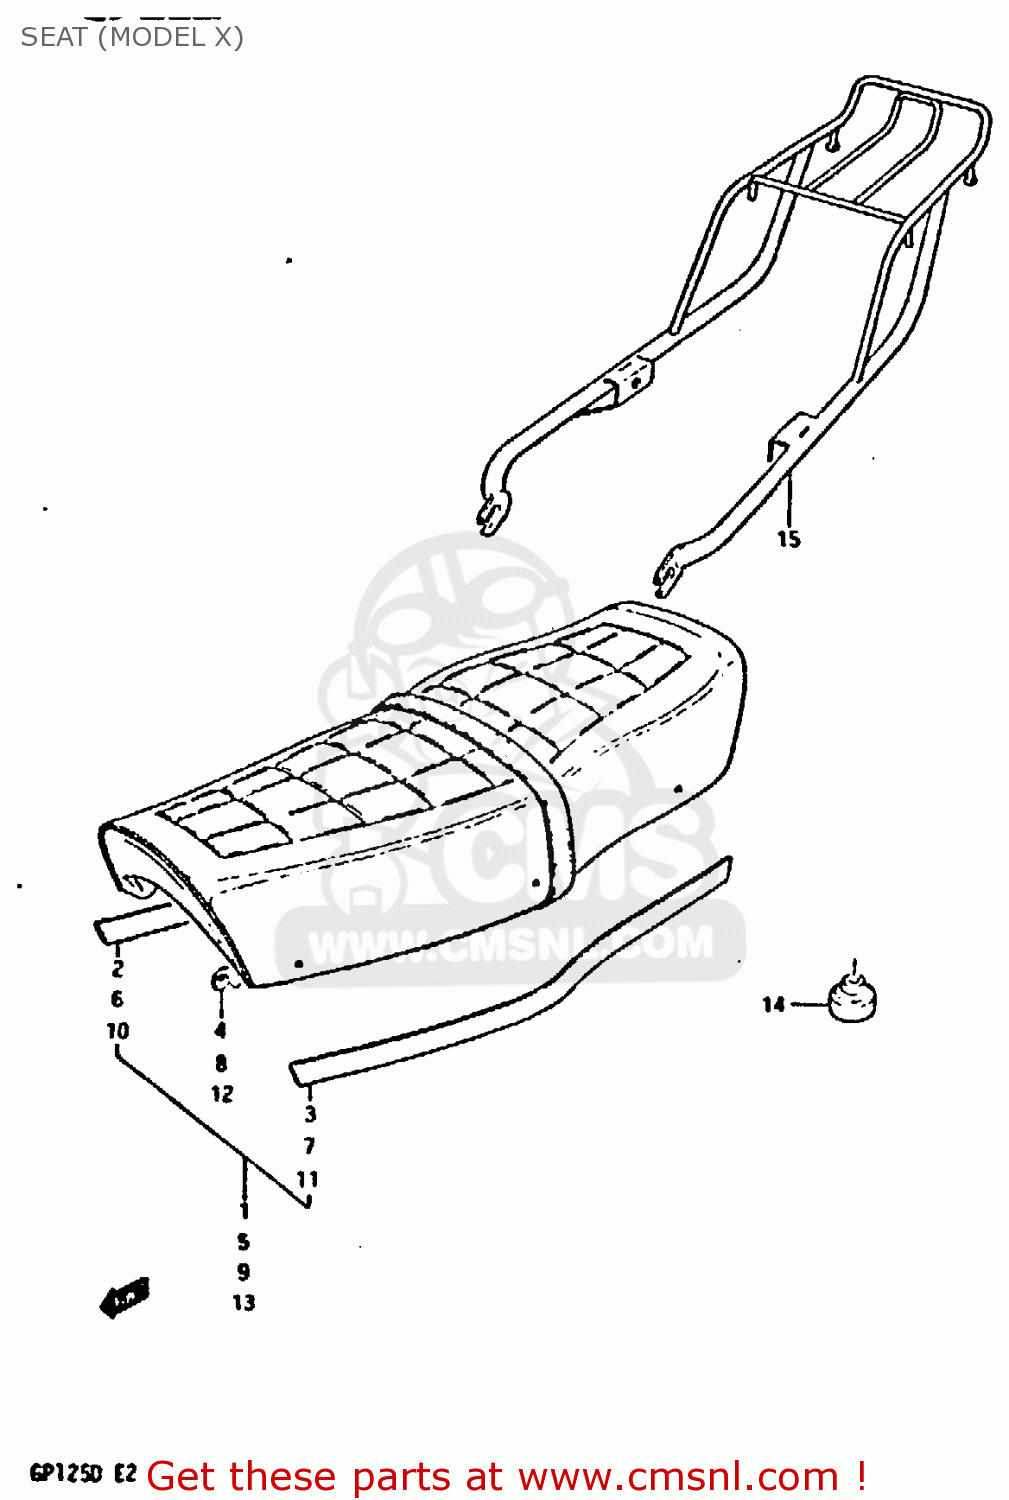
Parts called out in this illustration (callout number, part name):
1	SEAT ASSY
2	MOULDING, RH
3	MOULDING, LH
4	NUT
5	SEAT ASSY
6	MOULDING, RH
7	MOULDING, LH
8	NUT
9	SEAT ASSY
10	MOULDING, RH (BLACK)
11	MOULDING, LH (BLACK)
12	NUT
15	CARRIER,SPORT
